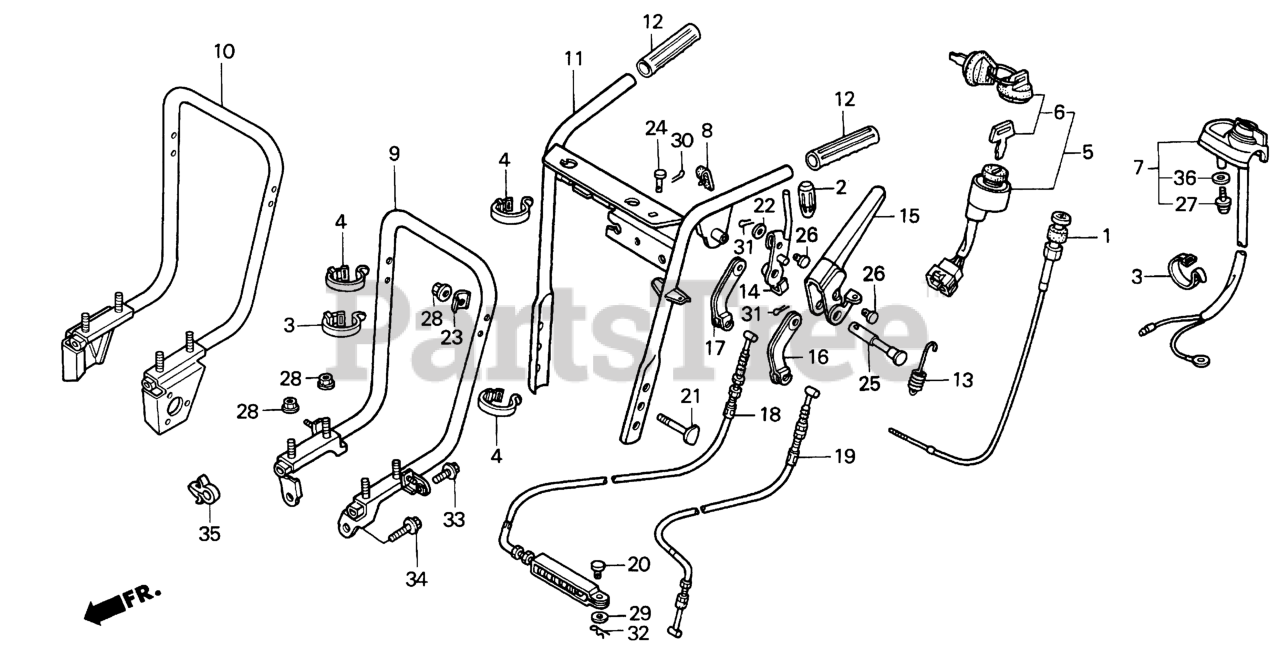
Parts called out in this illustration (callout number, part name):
2	GRIP, CHANGE LEVER
3	BAND B1, CABLE Use up to Frame SN 1001879.
4	BAND, CABLE
7	SWITCH ASSY., ENGINE STOP
8	STOPPER, CLUTCH LEVER
9	HANDLE (LOWER)
9	HANDLE (LOWER) *NH1*
11	PIPE, HANDLE (UPPER)
12	GRIP, HANDLE
13	SPRING, AUGER CLUTCH LEVER
14	LEVER, MAIN CLUTCH
15	LEVER, L. CLUTCH
16	ARM, CLUTCH
17	ARM, AUGER CLUTCH
18	CABLE, MAIN CLUTCH
19	CABLE, AUGER CLUTCH
20	PIN, SEAT HINGE
21	BOLT, HANDLE HOLDER (8X41)
21	BOLT, HANDLE HOLDER
22	WASHER, THRUST (10.5X16.5X1)
23	WASHER, FRAME JOINT
24	PIN (4X14)
25	PIN, CLUTCH LEVER
26	PIN (8X14)
27	SCREW, PAN (3X12)
28	NUT, FLANGE (8MM)
29	WASHER, PLAIN (6MM)
30	PIN, COTTER (1.6X10)
31	PIN, COTTER (1.6X25)
32	PIN, LOCK (6MM)
33	BOLT, FLANGE (8X16) Use from Engine SN 1000016.
34	BOLT, FLANGE (8X20) Use up to Engine SN 1609606.
35	CLIP, IGNITION WIRE (8MM)
36	WASHER, SPRING (3MM)
